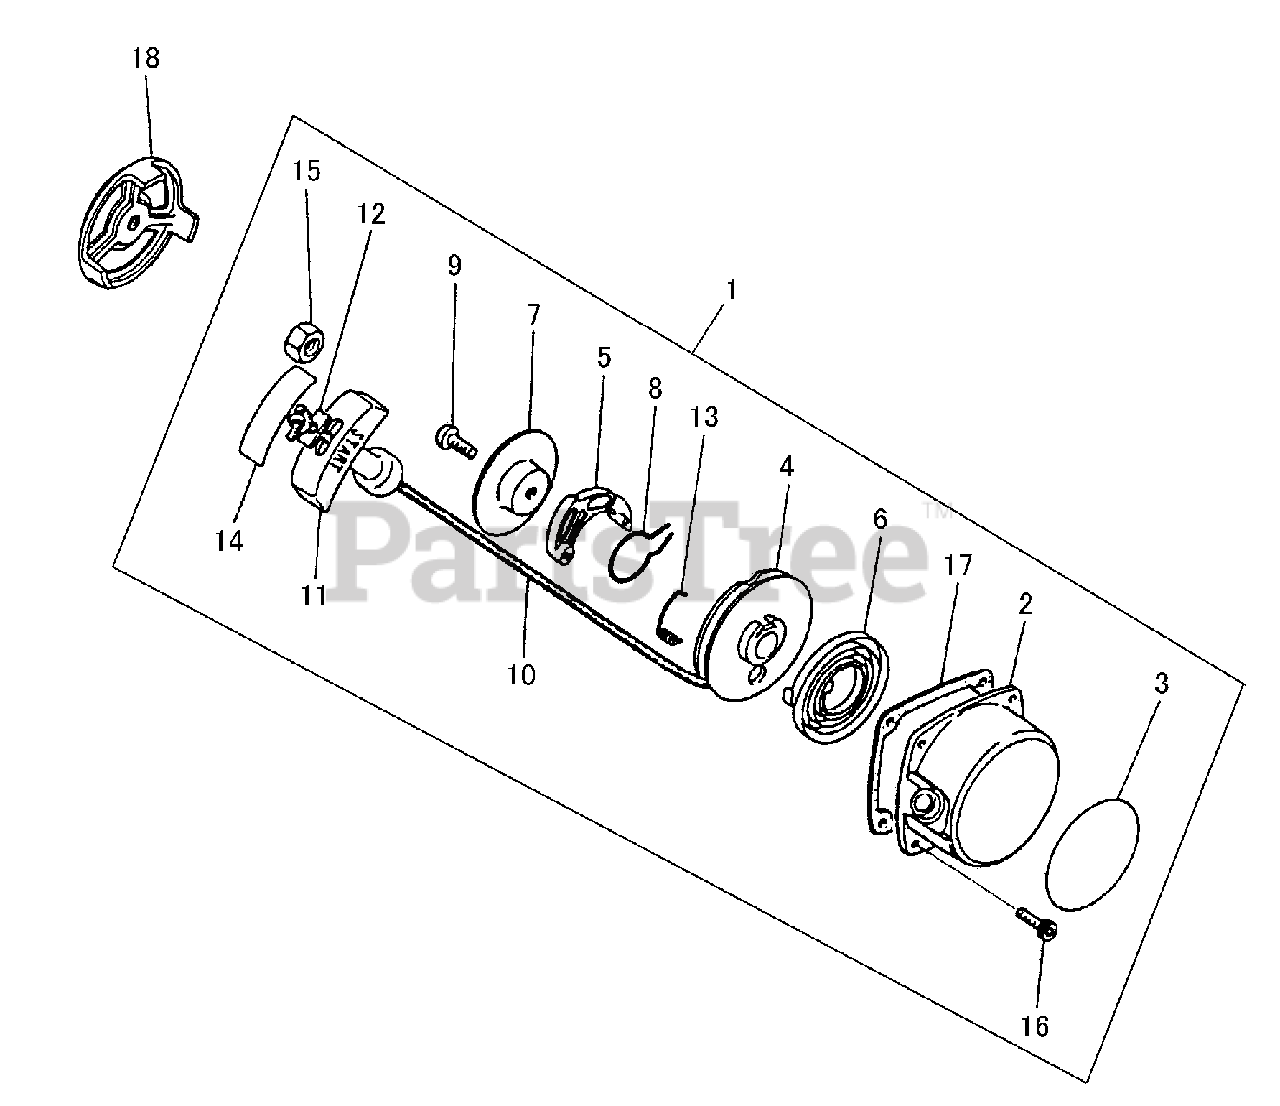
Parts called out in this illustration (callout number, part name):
1	STARTER ASSY
2	CASE, STARTER
3	LABEL - TRADE
4	REEL, ROPE
5	PAWL, STARTER
6	SPRING, REWIND
7	PLATE, STARTER
8	SPRING
9	SCREW
10	ROPE
11	GRIP, STARTER
12	RETAINER, ROPE
13	SPRING, RETURN
14	TAPE
15	NUT - 8
16	SCREW - 4X16
17	GASKET
18	CATCHER, STARTER
